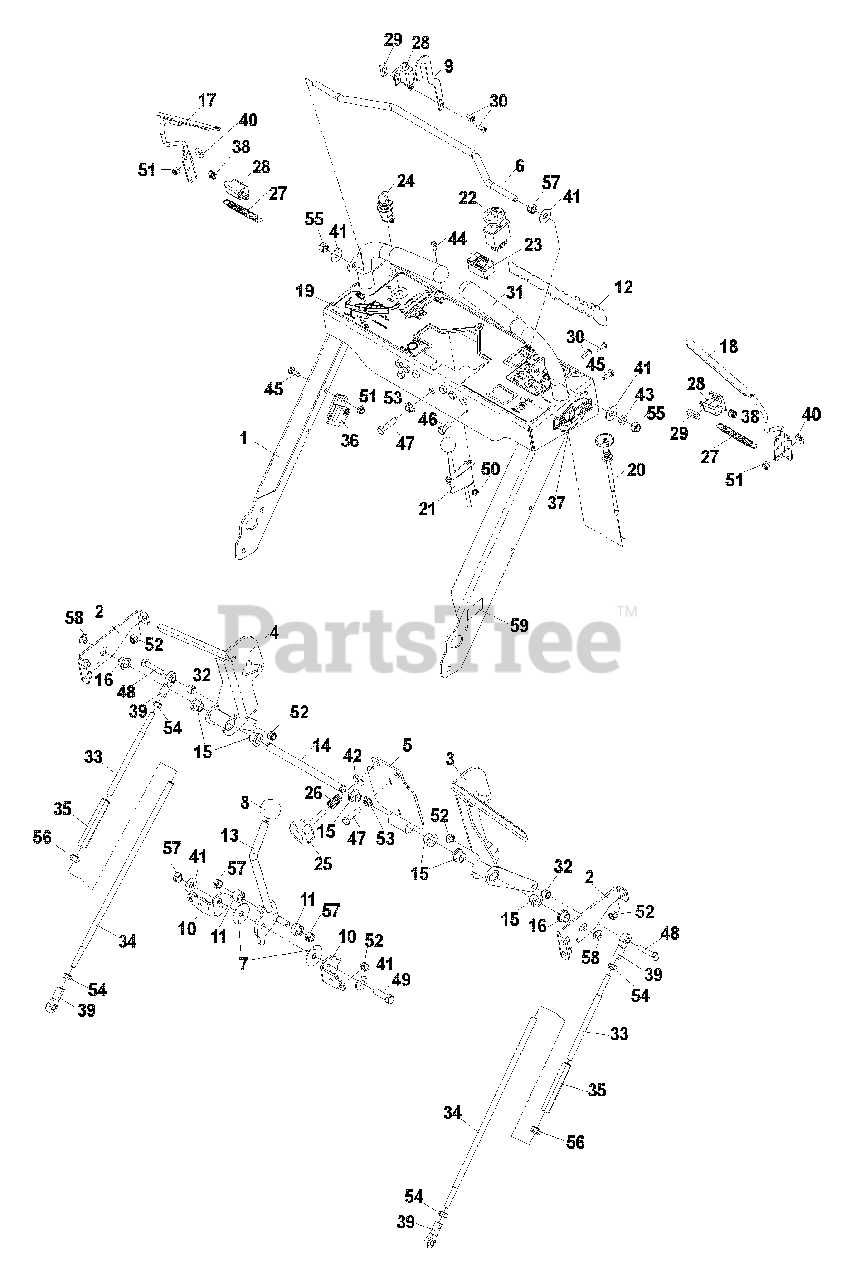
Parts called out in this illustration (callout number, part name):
1	HANDLE W/DECALS
3	DRIVE LEVER, LEFT
4	DRIVE LEVER, RIGHT
5	PLATE, TRACKING
7	WASHER, FRICTION
8	KNOB, SHIFT
9	ARM, NEUTRAL
10	PLATE, FRICTION
12	DECAL, HUSQVARNA
13	LEVER, GROUND SPEED
14	SHAFT, CROSS
15	BUSHING, NYLON FLANGED
16	BUSHING, FLANGE
17	OPERATOR, RIGHT
18	OPERATOR, LEFT
19	DECAL, CONSOLE, ETS
20	CABLE, CHOKE
21	CABLE, THROTTLE
22	SWITCH, CLUTCH
24	SWITCH, KEY
25	KNOB, ADJ.
29	PLATE, TAPPED
30	SCREW, #10-24 X 5/8 MACH.
32	SPACER, PULLEY
33	LINKAGE, SHORT
34	LINKAGE, LOWER
35	TURNBUCKLE, 3/8
37	DECAL, ETS
38	SPRING, SWITCH
39	BALL END, RIGHT
40	WASHER, 1/4
41	WASHER, 3/8
42	WASHER, 5/16
43	LOCKWASHER, 3/8
44	HCS, #10-24 X 1/2
45	HCS, 1/4-20 X 5/8, GR5
46	HCS, 5/16-18 X 3/4, GR5
47	HCS, 5/16-18 X 1 1/4, GR5
48	HCS, 5/16-18 X 1 1/2, GR5
49	HCS, 3/8-16 X 1 1/4, GR5
50	NUT, #10-24, NYLOC
51	NUT, 1/4C, NYLOC
52	NUT, 5/16C, NYLOC
53	NUT, 5/16C
54	NUT, 5/16F
55	NUT, 3/8C, NYLOC
57	NUT, 3/8C, CENTER LOCK
58	E-RING, 1/2"
59	DECAL, DUAL HEIGHT
